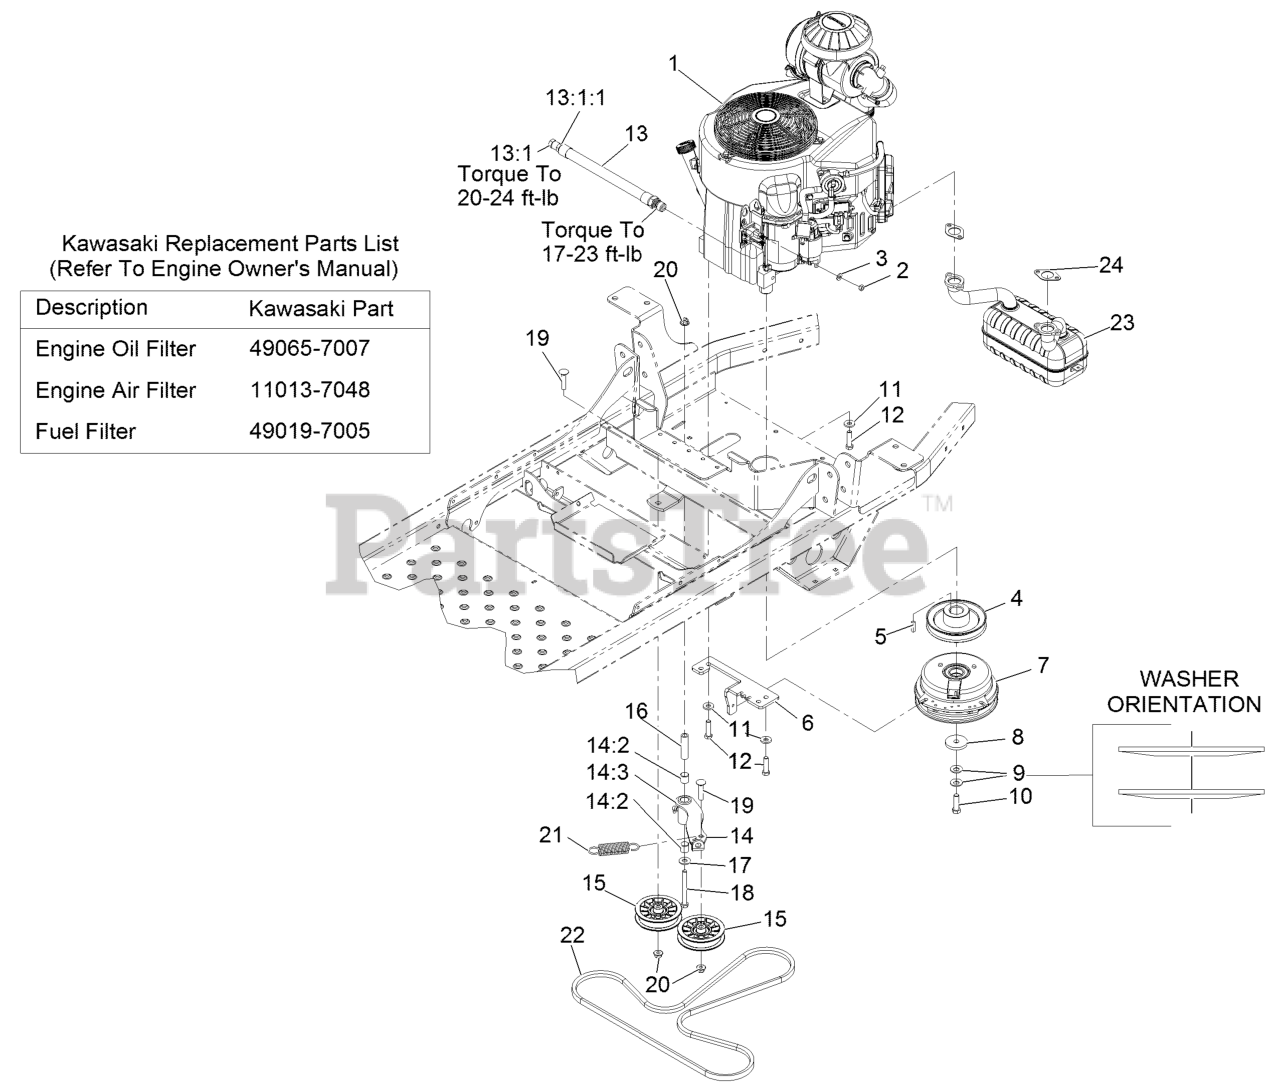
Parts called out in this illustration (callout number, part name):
1	Engine-Kawasaki
2	NUT-HEX
3	WASHER-FLAT
4	SHEAVE-PUMP, DRIVE
6	ANCHOR-CLUTCH
8	WASHER-CLUTCH
9	WASHER-SPRING
10	SCREW-HH 7/16-20 X 1 1/2 W/LOCTITE
11	WASHER-BELLEVILLE
12	SCREW-HH
13	ENGINE OIL DRAIN HOSE ASM
13:1	PLUG-HH
13:1:1	O-RING
14:2	SLEEVE-BEARING
14:3	FITTING-GREASE, 90 DEG
15	PULLEY-FLAT IDLER
16	BUSHING-PIVOT, IDLER
17	WASHER-FLAT
18	SCREW-CARR
19	SCREW-CARR
20	NUT-HF, NI
21	SPRING-EXTENSION
22	V-BELT
23	MUFFLER-KAWASAKI
24	GASKET-EXHAUST
